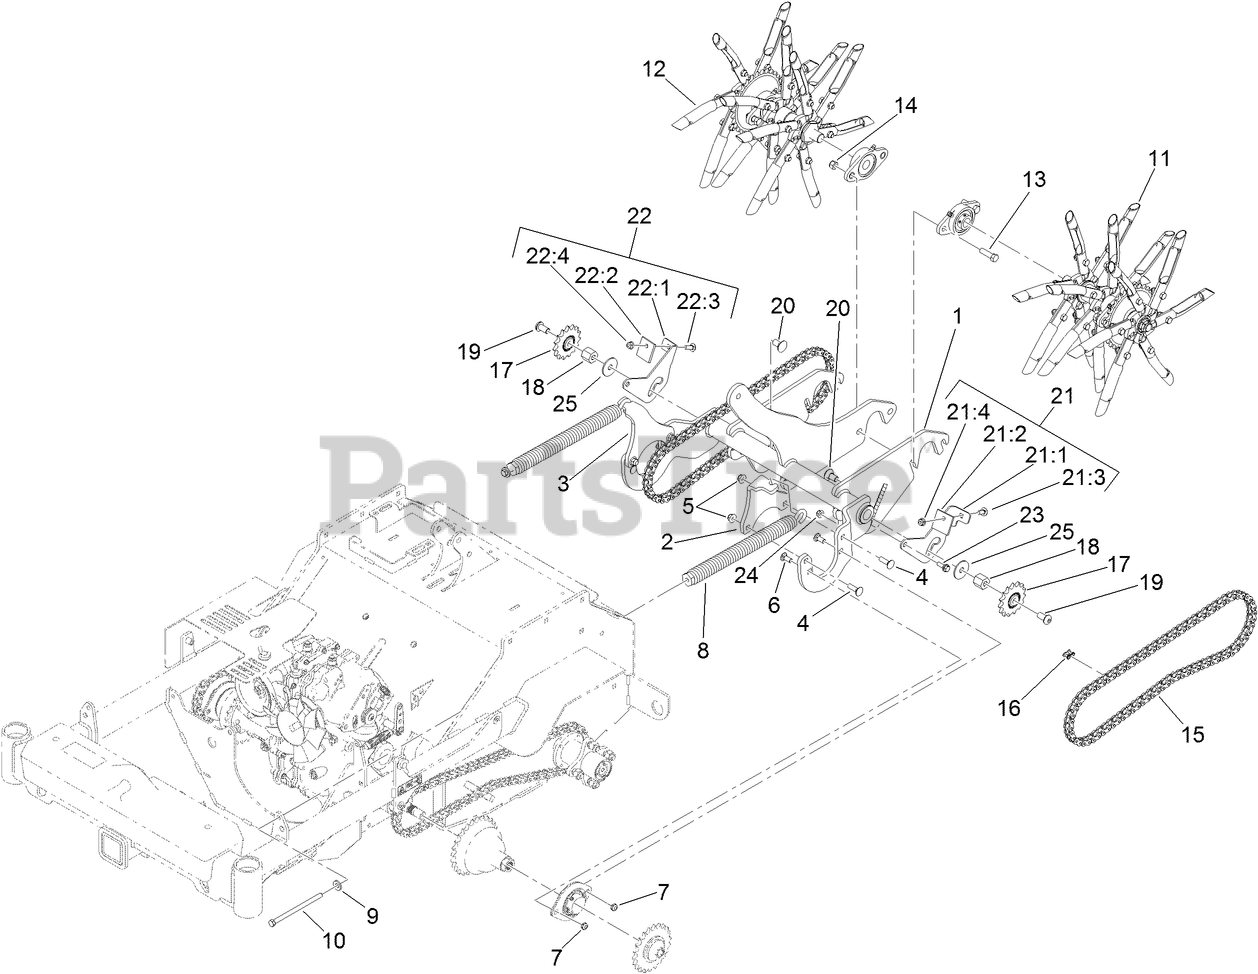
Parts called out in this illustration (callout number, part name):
1	LIFT-TINE
2	ARM-SPRING, LH
3	ARM-SPRING, RH
4	BOLT-CARR
5	NUT-HF, NI
6	BOLT-CARR
8	SPRING-EXTENSION
9	WASHER-BELLEVILLE
10	BOLT-TAP, HH
11	LH TINE WHEEL ASM
12	RH TINE WHEEL ASM
13	SCREW-HH
14	NUT-LOCK, NI
15	CHAIN-ROLLER
16	LINK-CONNECTING
17	SPROCKET-IDLER, 15T
18	SPACER
19	SCREW- PAN SOCKET HEAD
20	SCREW-HH
21	LH DEBRIS DEFLECTOR ASM
21:1	BRACKET-DEFLECTOR, DEBRIS (LH)
21:2	DEFLECTOR-DEBRIS
21:3	BOLT-CARR
21:4	NUT-HF, NI
22	RH DEBRIS DEFLECTOR ASM
22:1	BRACKET-DEFLECTOR, DEBRIS (RH)
22:2	DEFLECTOR-DEBRIS
22:3	BOLT-CARR
22:4	NUT-HF, NI
23	SCREW-SHOULDER
24	NUT-HF, NI
25	WASHER-FLAT
